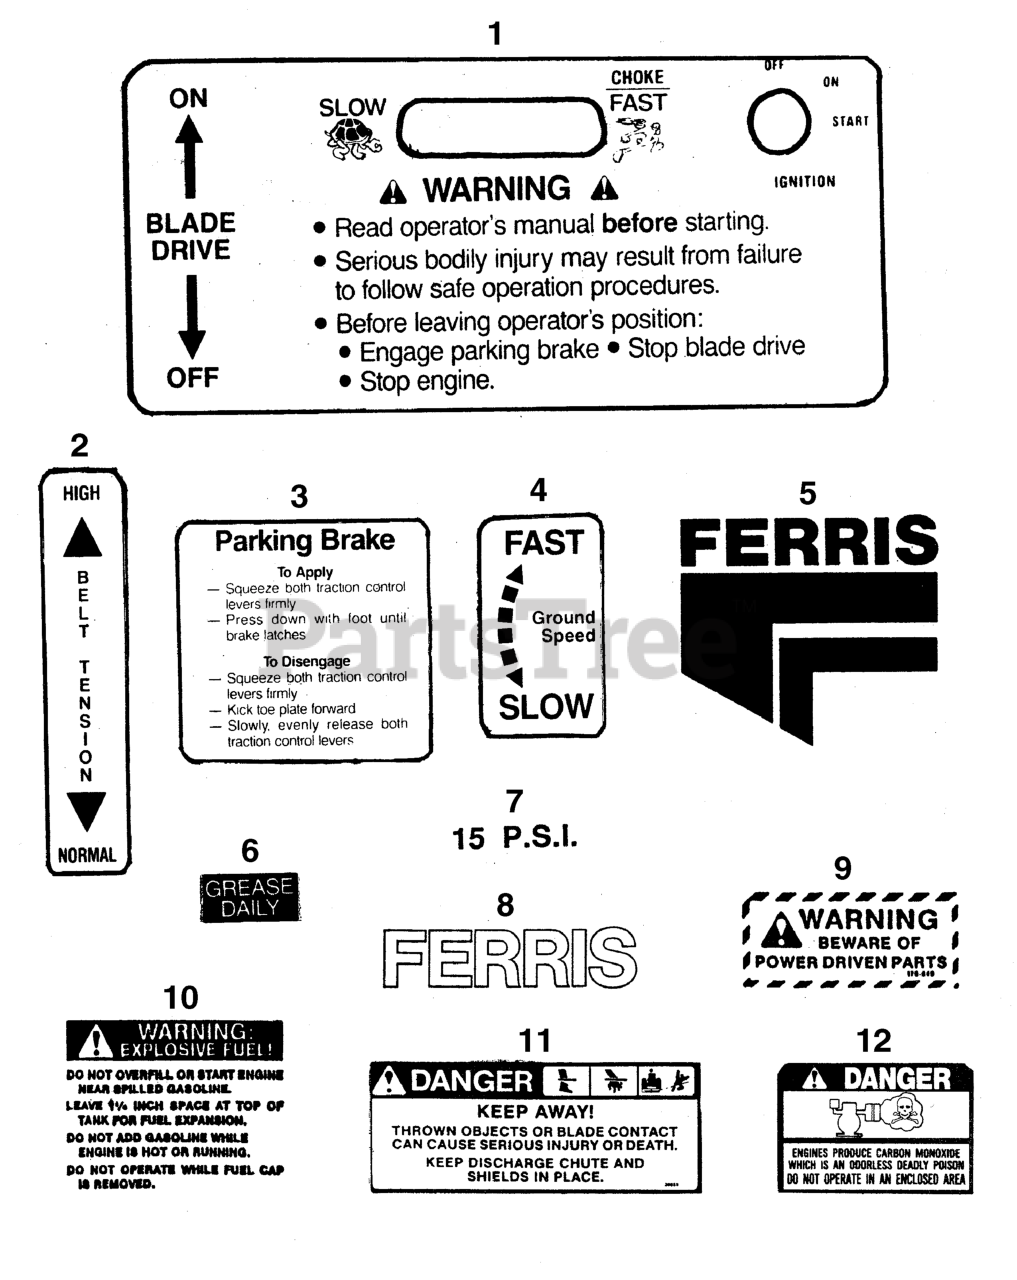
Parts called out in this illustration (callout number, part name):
1	DECAL, Operation
2	DECAL, Belt Tension
3	DECAL, Parking Brake
4	DECAL, Ground Speed
5	DECAL, Ferris Logo, 10-3/4"
6	DECAL, Grease Daily
7	DECAL, 15 P.S.I.
8	DECAL, FERRIS TEXT & LOGO
9	DECAL, Warning
10	DECAL, EXPLOSIVE FUEL
11	DECAL, DANGER DO NOT OPERATE W/O DEFLECT
12	DECAL, Danger, Carbon Monoxide
